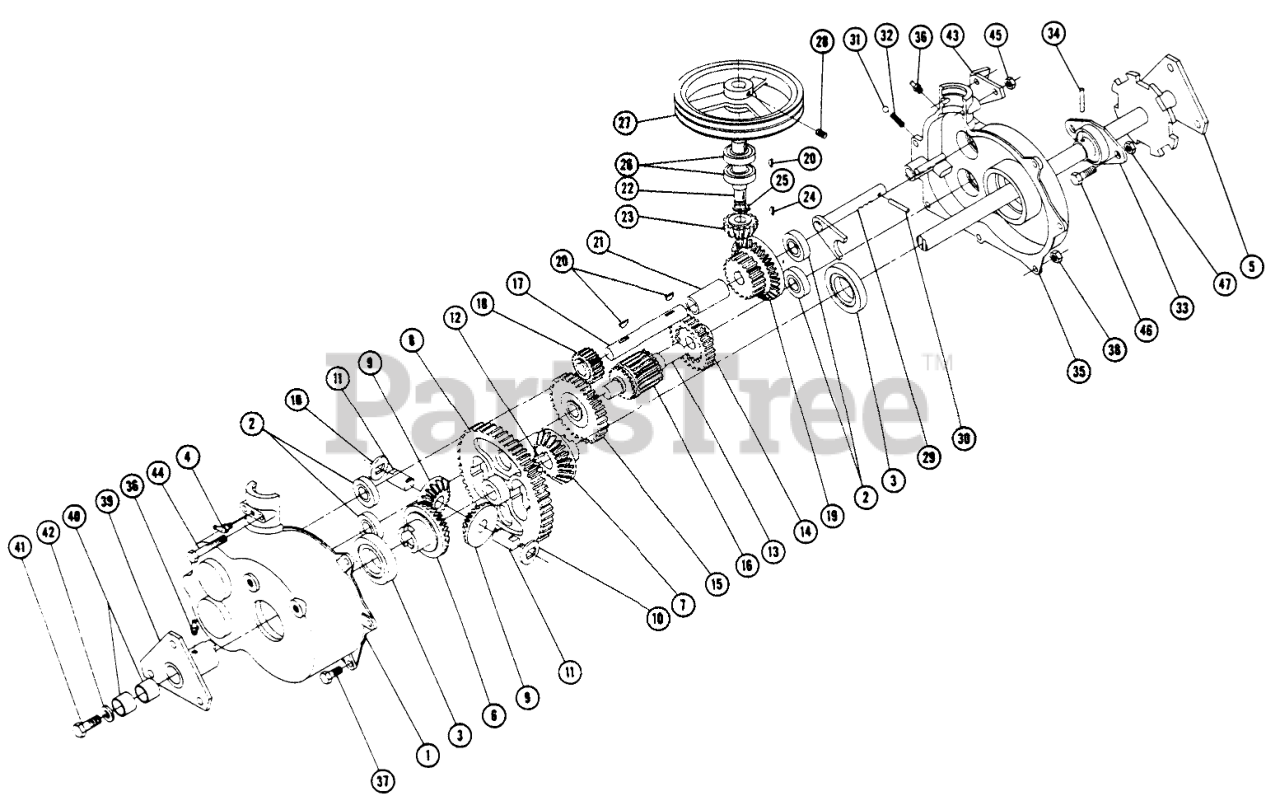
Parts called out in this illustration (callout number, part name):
4	FITTING-GREASE
5	Ass-y. Axle
6	4XC6475 GIS ROTARY
12	WOODRUFF KEY
17	Shaft-Hi Low Pinion
20	Key
21	Spacer
22	Shaft Input
24	WOODRUFF KEY
28	Set Screw 1/4-20 x 3/8
30	PIN-SPIROL
31	BALL-DETENT
34	Spirol Pin
37	Bolt, 5/16-18 X 7/8
38	Nut 5/16-18
39	Ass-y Hub Flange
40	BUSHING-BRONZE
41	Bolt 3/8-16 x 3/4 Hex
42	WASHER
43	Bracket-Shift Rod
44	Bolt Hex 5/6-18 X 2-1/2
45	Nut-Nylok
46	Bolt Hex 3/8-16 x 5/8
